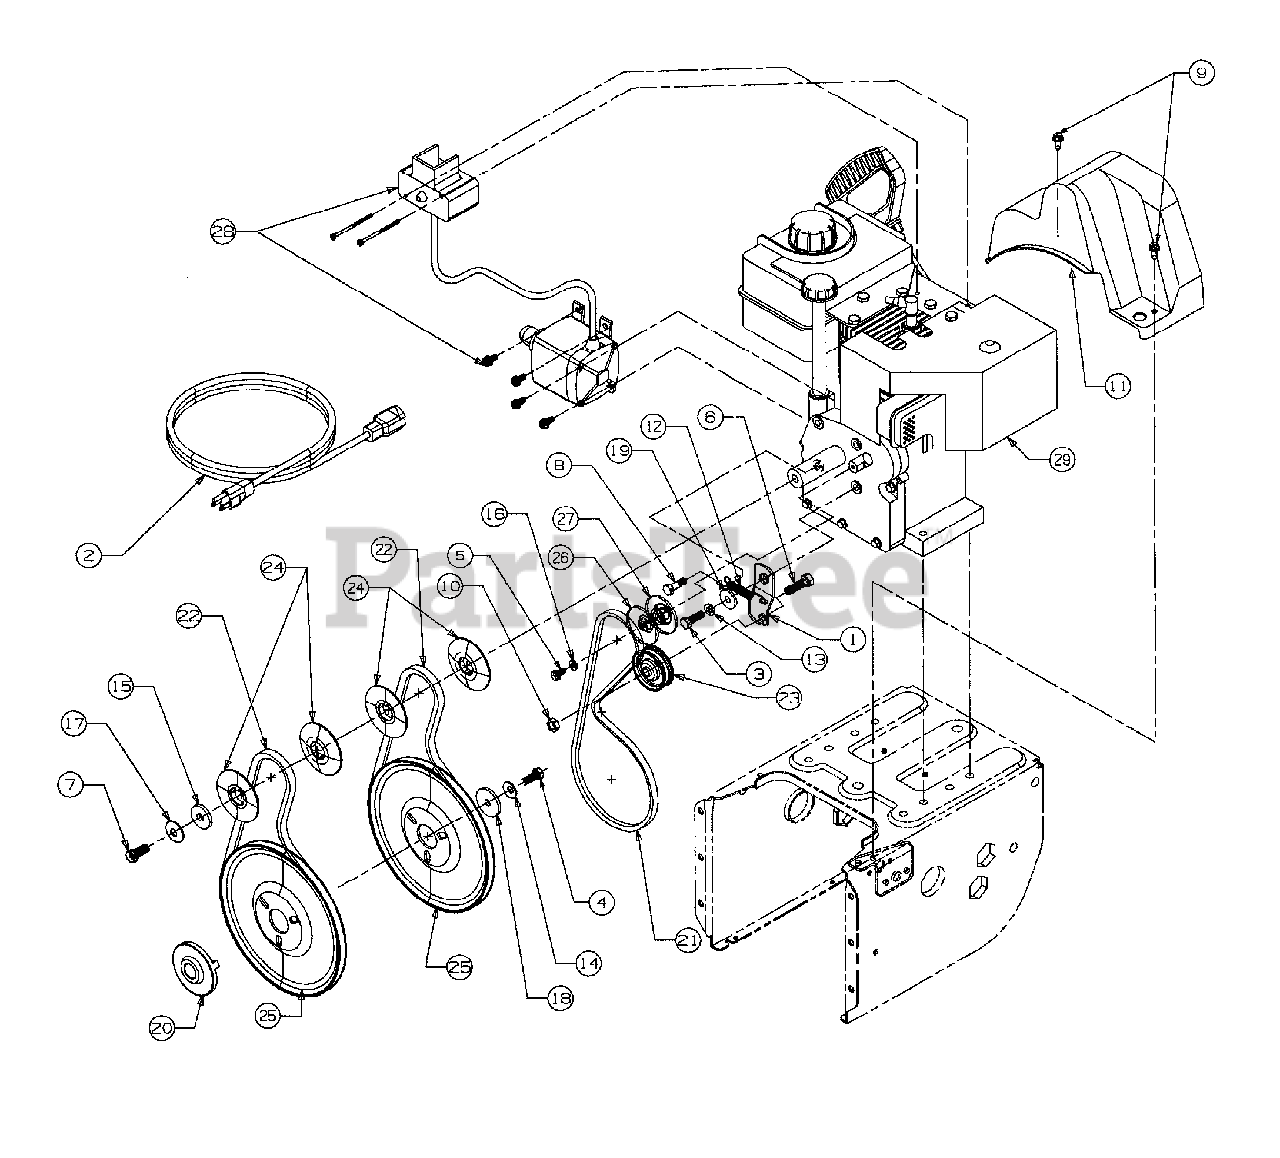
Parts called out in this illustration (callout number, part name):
3	Screw - Hex
4	Screw - Hex
5	Screw - Hex
6	Screw - Hex
7	Screw - Hex
8	Screw - Hex
9	Screw - Hex
10	Nut - Hex
11	Cover - Belt
12	Spring
13	Washer - Lock
14	Washer - Bell
15	Washer - Flat
16	Washer - Lock
17	Washer - Bell
18	Washer - Flat
19	Spacer
20	Adapter - Pulley
21	V-Belt
22	V-Belt
23	Idler - Flat
24	Pulley Half
25	Pulley - Auger
26	Pulley Half
27	Pulley Half
28	Electric Start Kit
